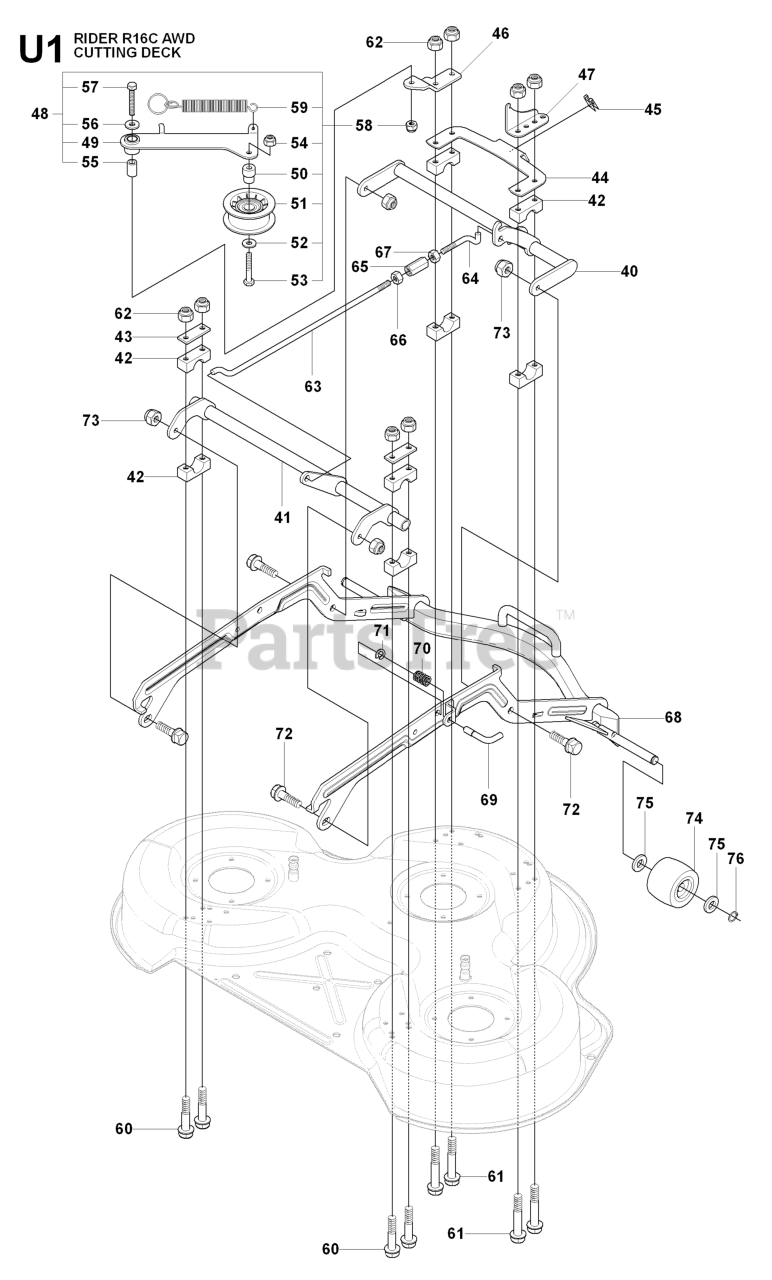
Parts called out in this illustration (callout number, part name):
51	PULLEY
54	LOCKNUT M8
57	SCREW
58	LOCKNUT M8
62	LOCKNUT M8
67	NUT
73	LOCKNUT M8
74	DECK ROLLER, FRONT
76	RETAINING RING SGA 15
